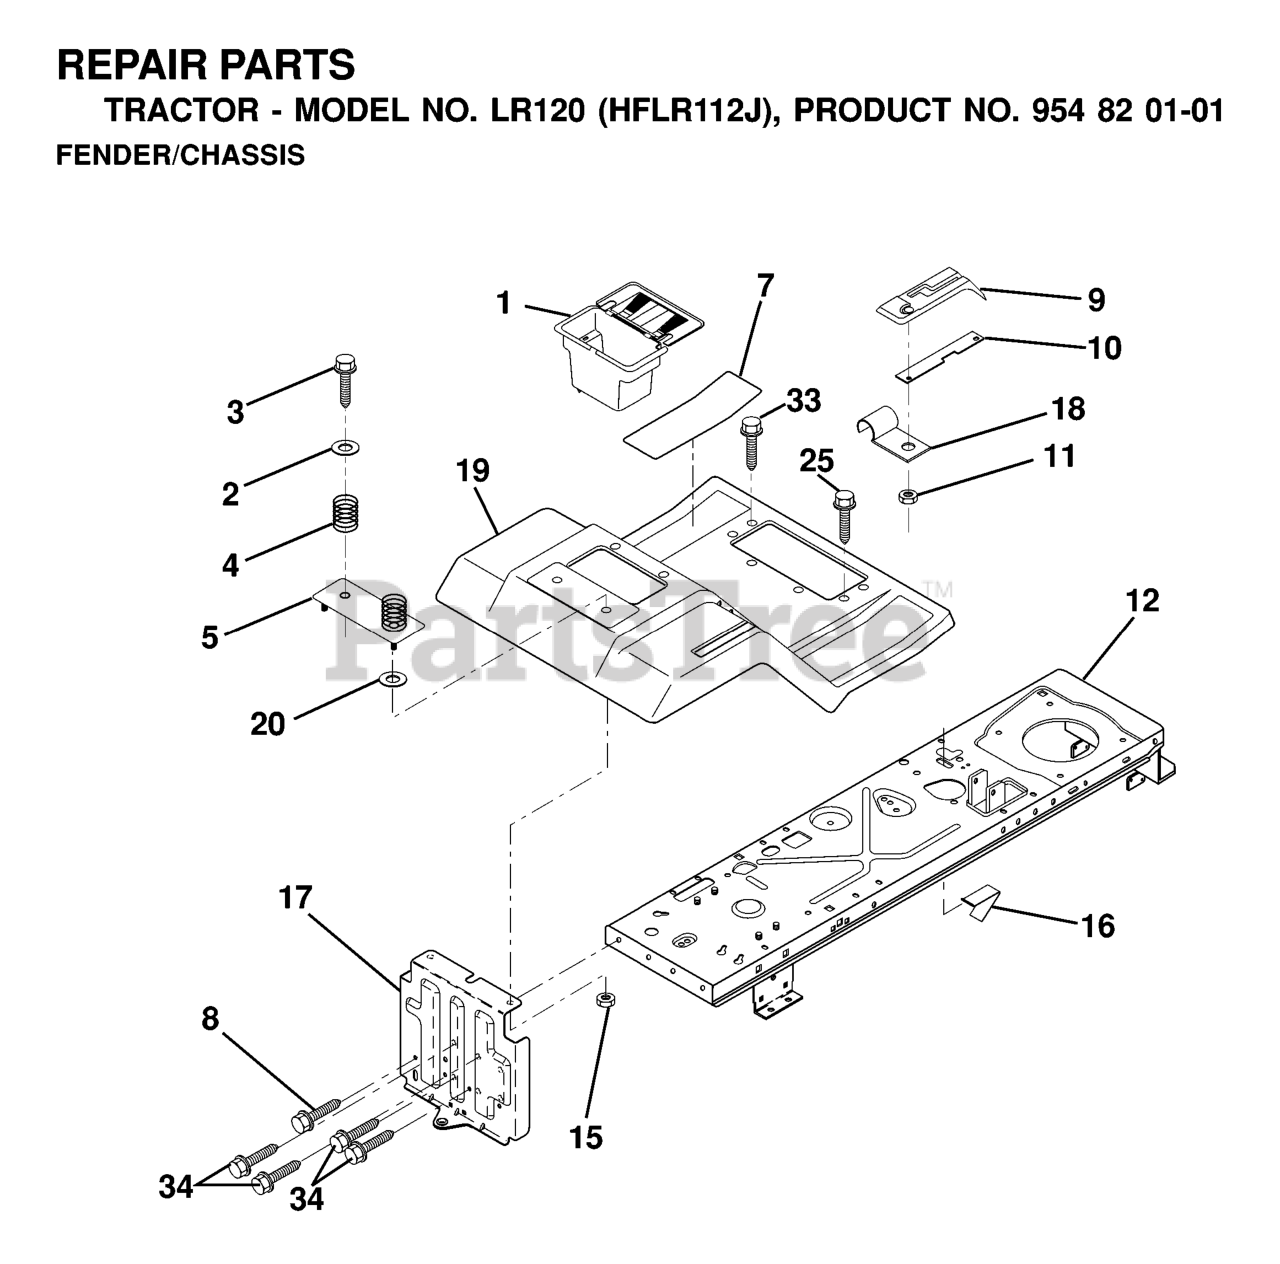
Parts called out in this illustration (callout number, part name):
1	CASE BATTERY MECH HINGE
2	WASHER
3	SCREW
4	SPRING COMPRESSION
5	PLATE ASM BATTERY
7	PAD FOOTREST
8	SCREW 5/16"
9	CONSOLE.SHIFT CONTROL
10	BAR, SHIFT LOCK
11	NUT.PUSH.3/16
15	Nut, Keps Blk Hex 1/4-20 UNC
16	SWITCH ACTUATOR
18	CLIP,INSULATOR
19	FENDER/FOOTREST
20	WASHER
25	Screw Tapping 5/16-18 Unc
33	Screw Hex Wsh Thdroll 5/16-18 x 1
34	SHOULDER BOLT 5/16-18TT
